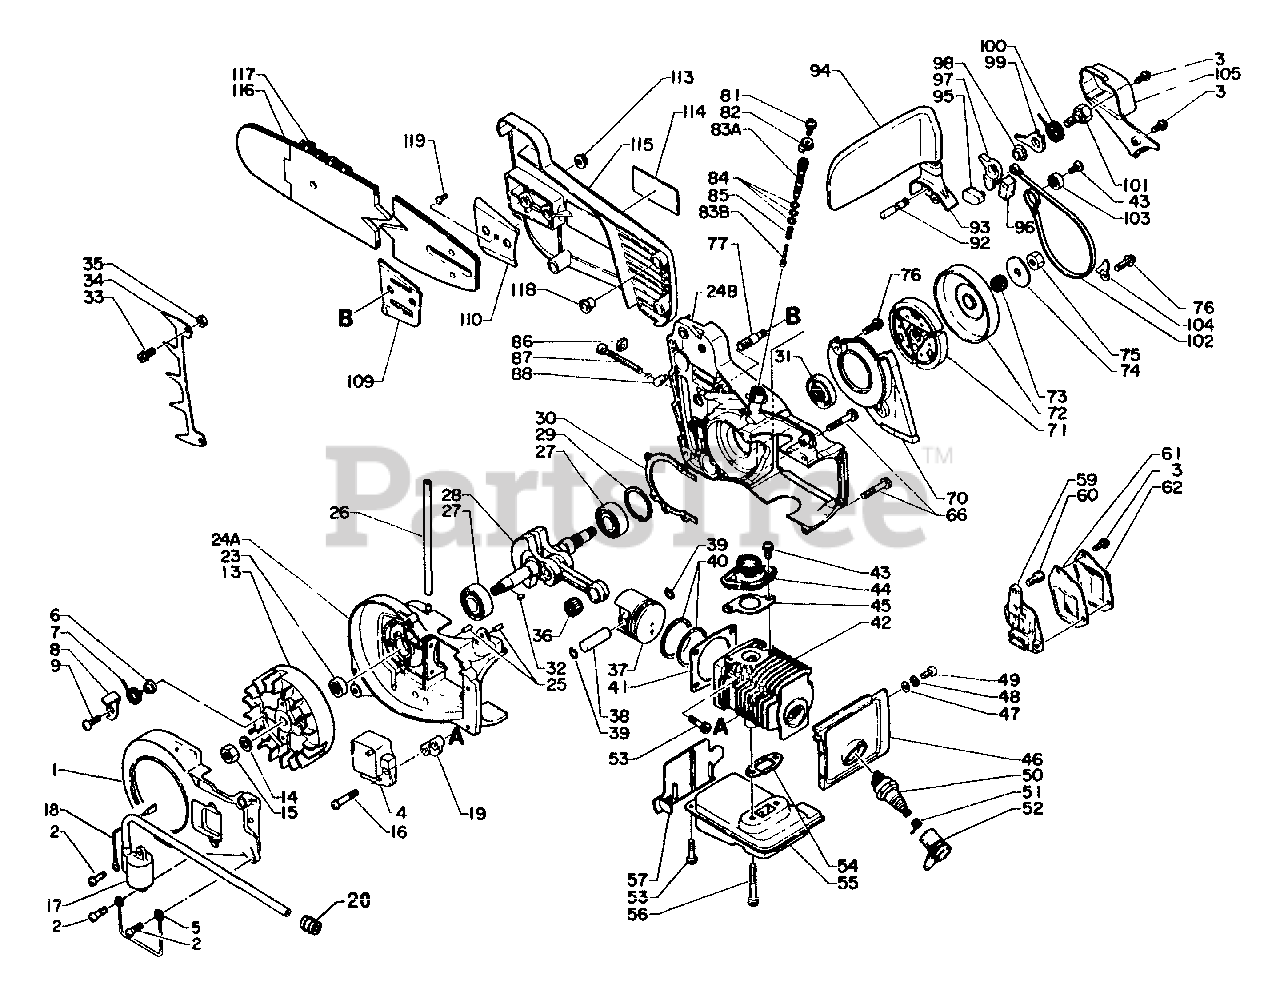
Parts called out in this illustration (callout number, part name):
1	COVER, FAN
2	SCREW 4×16
3	SCREW 4×12
4	COIL, IGNITION
5	LEAD - GROUND
7	SPRING, RETURN
8	PAWL, STARTER
9	SCREW
13	FLYWHEEL
16	SCREW
17	COIL, IGNITION
18	LEAD
23	SEAL, OIL
24	CRANKCASE KIT
25	PIN, LOCATING 4
26	PIPE, FUEL 3×6×135L
27	BEARING, BALL 6202
28	CRANKSHAFT ASSY
29	RING, SNAP 35
30	GASKET, CRANKCASE
30	WASHER, THRUST
31	SEAL, OIL 18
32	KEY, WOODRUFF
33	BOLT 5×12
34	BUMPER, SPIKED
35	NUT M5
36	BEARING, NEEDLE
37	PISTON
38	PIN, PISTON
39	RING, SNAP 8
40	RING, PISTON
41	GASKET, CYLINDER
42	CYLINDER
43	SCREW 5×10
44	ADAPTER, INTAKE
45	GASKET, INTAKE
46	COVER, CYLINDER
47	WASHER 4 MM
48	WASHER, SPRING 4 MM
49	SCREW 4×12
50	SPARK PLUG - BPM6A
51	TERMINAL, SPARK PLUG
52	CAP, SPARK PLUG
53	BOLT 5×20
54	GASKET, EXHAUST
56	BOLT 5×40
57	INSULATOR
59	ADAPTER
60	BOLT 5×12
61	SCREEN, SPARK ARRESTER
62	GUIDE, EXHAUST
66	BOLT 5×30
70	PLATE
71	CLUTCH ASSY
72	DRUM, CLUTCH
73	BEARING, NEEDLE
74	WASHER, CLUTCH
75	LOCKNUT
76	SCREW 5×16
81	SCREW 5×10
82	WASHER, LOCK
83	AUTO-OILER ASSY
87	SCREW, ADJUSTER
88	TENSIONER
93	COVER, BRAKE
94	HANDLE
95	RESET, BRAKE
96	SEAL
97	CONNECTOR
100	SPRING, RETURN
102	BAND, BRAKE
103	ADJUSTER, BRAKE BAND
104	RETAINER, BRAKE BAND
109	PLATE, GUIDE - INNER
110	PLATE, GUIDE - OUTER
113	NUT - 6 -- FLANGE
114	LABEL - ECHO
115	GUARD, SPROCKET
116	GUIDE BAR - 16E50
117	SAWING CHAIN - 33LG-66×
118	PIN, DOWEL
119	SCREW 3×6
